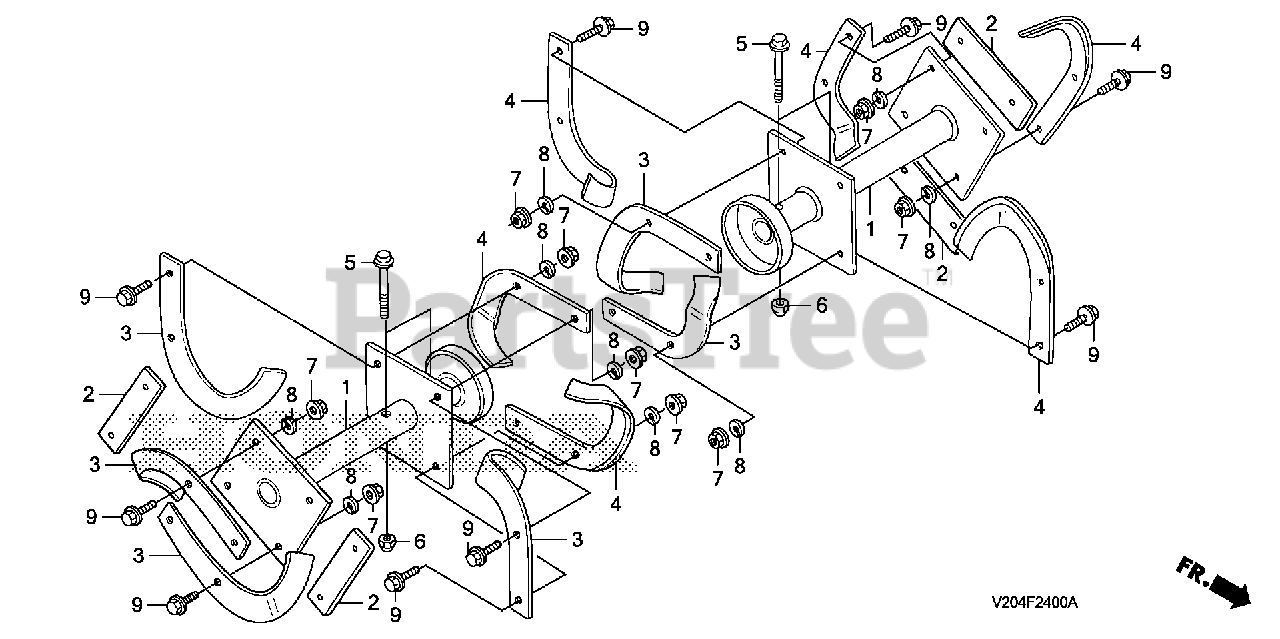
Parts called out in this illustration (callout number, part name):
1	SHAFT, ROTARY TINE *NH105* (MAT BLACK)
2	PLATE, TINE *NH105*
2	PLATE, TINE *NH105* (MAT BLACK)
3	TINE A, ROTARY
4	TINE B, ROTARY
5	BOLT, FLANGE (10X58)
6	NUT, SELF-LOCK (10MM)
7	NUT, FLANGE (10MM)
8	WASHER, SPRING (10MM)
9	BOLT, FLANGE (10X30)
